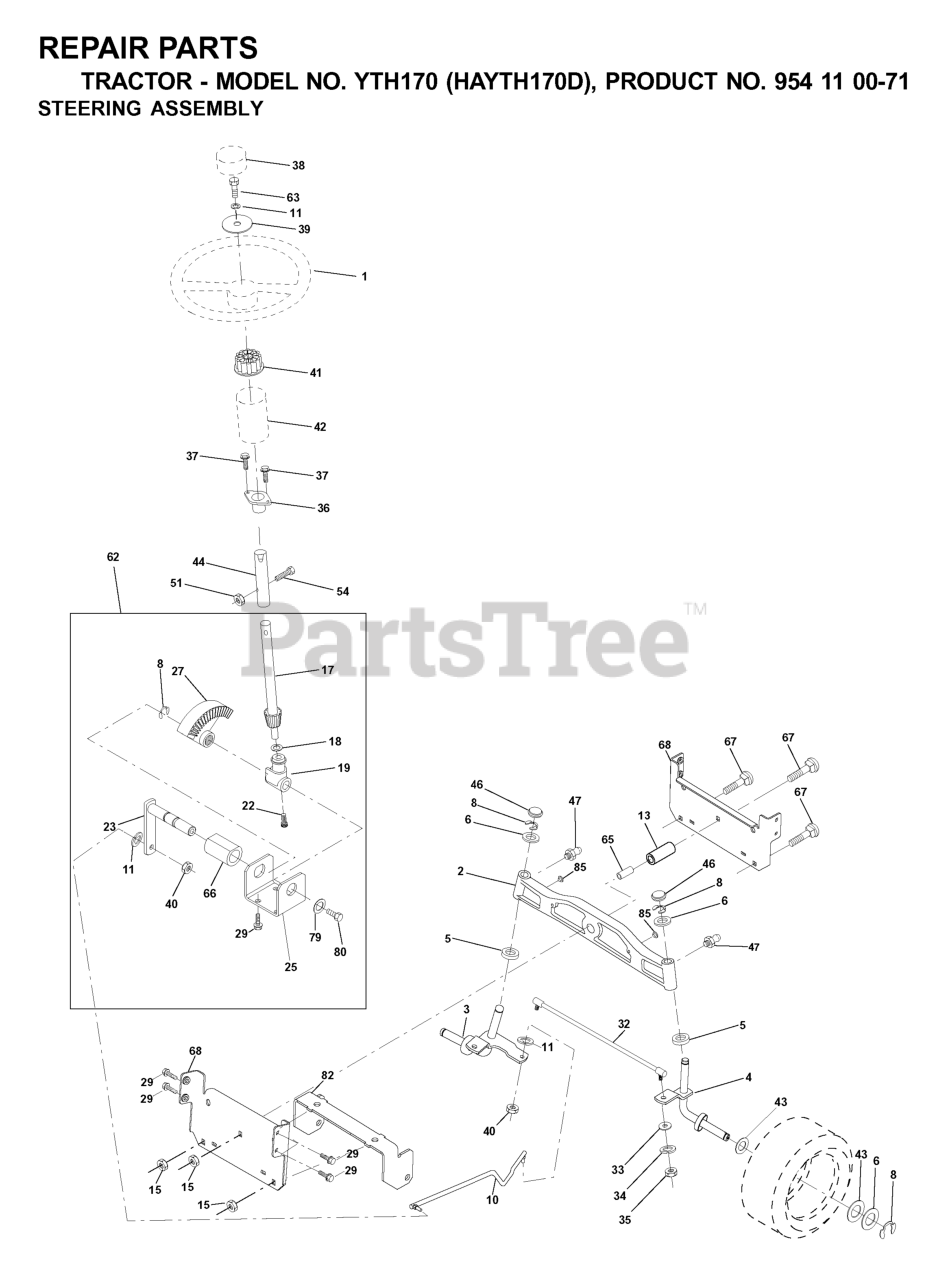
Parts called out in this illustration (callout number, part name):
1	STEERING WHEEL
2	AXLE
3	SPINDLE.ASM.LH.15"TIRES
4	SPINDLE.ASM.RH.15"TIRES
5	THRUST WASHER
10	DRAGLINK.15".TIRES
11	WASHER, LOCK 3/8
13	TUBE, PIVOT AXLE
15	NUT
17	SHAFT ASM STEERING
18	THRUST WASHER
19	STEERING SHAFT SUPPORT
22	SCREW.HX.WSH.HD
23	SHAFT ASSY PITTMAN
25	BRACKET STEERING
27	GEAR.SECTOR
29	SCREW 3/8-16X3/4
33	WASHER M
34	WASHER.LOCK.HVY.HLCL.SPR.5/16
35	NUT, CROWNLOCK
36	BUSHING, STEERING
37	SCREW.TT.#10-32X.5.3/8.FLANGE
38	INSERT,STR WHEEL
39	WASHER 13/32 X 2-3/8 X 12GA
40	GRIPCO NUT
41	ADAPTER LT
42	BOOT STEERING
44	EXT SHAFT STEERING
46	CAP.SPINDLE.BLACK
47	ZERK M
51	NUT.71038.31-18.HEX.NYLOCK
54	BOLT.5/16-18X1-1/4 FULL.THREAD
62	STEERING KIT
65	SPACER BRACE AXLE
66	BEARING ARM
67	BOLT
68	BRACE.AXLE.15"TIRES
79	WASHER
80	BOLT.HX.NYLON3/8-16X
82	BRACKET
85	FASTENER.XMAS.TREE
